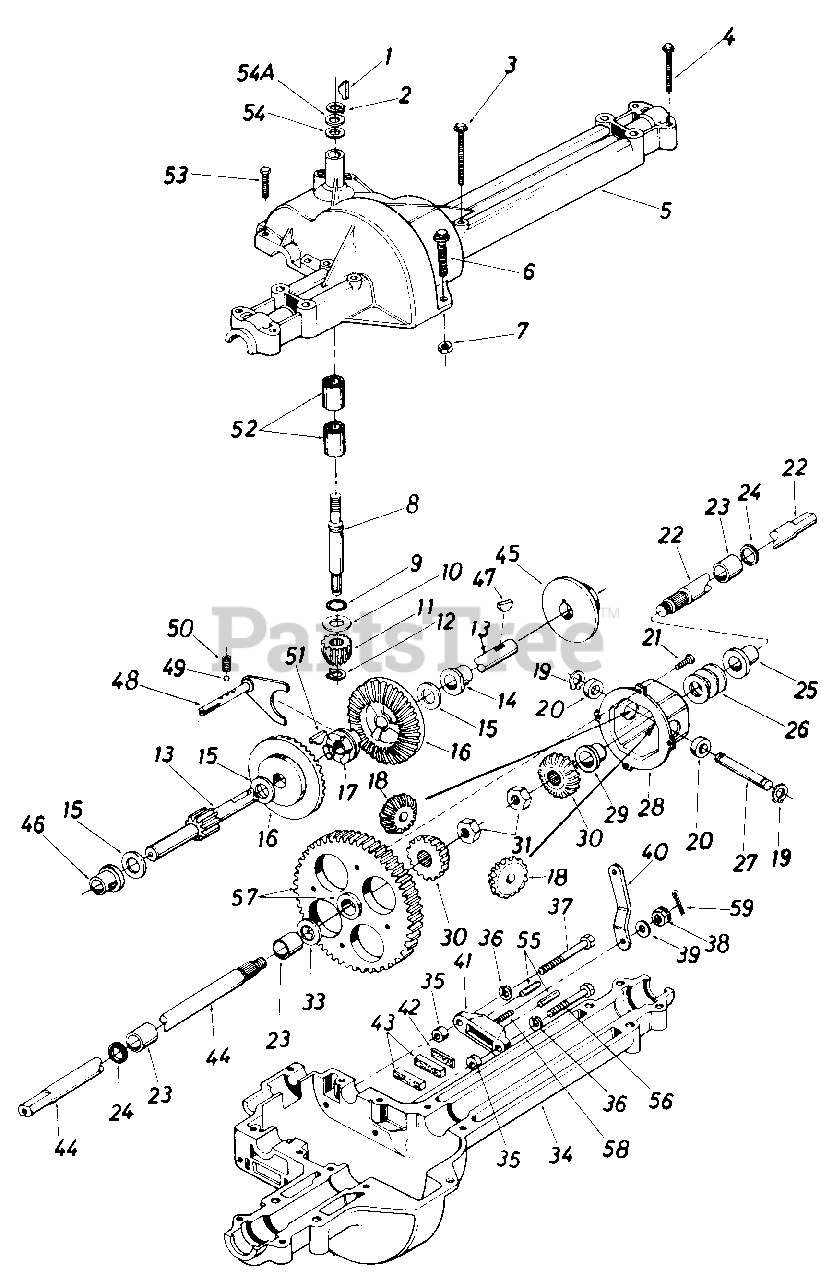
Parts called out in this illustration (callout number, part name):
1	#4 Hi-Pro Key 3/32 x 518" Dia.
2	Snap Ring .625" Shaft
3	Hex Bolt 1/4-20 x 1.75" Lg.
4	Hex Bolt 1/4-20 x 1.25" Lg.
5	Upper Housing
6	Hex Fl-Bolt 1/4-20 X .75" Lg.
7	Hex Nut 1/4-20 Thd.
8	Input Shaft
9	Squtle Seai 518" I.D.
10	Thrust Washer 518" I.D. x 1.25" O.D.
11	Pinion Input 14T
12	Retaining Ring 7116" Ext.
13	Drive Shaft-R.H.
14	Flange Brg. 518" I.D. x 3/4" Lg.
15	Fl-Wash.
16	Bevel Gear 42T
17	Clutch Collar
18	Miter Gear 15T
19	Snap Ring
20	Thrust Bearing 1/2" I.D. x 1.0" O.D.
21	Pan Head Scr. 1/4-20 X .50" Lg. w/Patch
23	Sleeve Bearing 3/4" I.D. x 1.0" Lg.
24	Oil Seal 3/4" I.D.
25	Flange Bearing 3/4" I.D. x 15/1 6" Lg.
26	Fl-Wash. .760" I.D. x 1.49" O.D.
27	Cross Shaft
28	Differential Housing Ass'y.
30	Miter Gear-H.D.
31	Hex Ins. L-Nut 1/2-20 Thd.
33	Fl-Wash. .75" I.D. x 1.5" O.D.
34	Lower Housing
35	Spacer .53" O.D. x 3/8" Lg.
36	L-Wash. 1/4" I.D.
37	Hex Bolt 1/4-20 x 1.50" Lg. (Grade 5)
38	Castle Nut 5/16-24 Thd.
39	Fl-Wash. .34" I.D. x .875" O.D.
40	Actuating Arm-R.H.
42	Puck Plate
43	Brake Puck
46	Flange Bearing 5/8" I.D. x 15/16" Lg.
47	Woodruff Key 3/16 Y 5/8 HT
48	Shift Fork Ass'y.
49	Ball Detent.250" Dia.
50	Spring Detent
51	#9 Hi-Pro Key 3/16" x 3/4" Dia. HT
52	Needle Brg. 5/8" I.D. x 1/2" Lg.
53	Hex Bolt 1/4-20 x 1.00" Lg.
54	Fl-Wash. 5/8" I.D. x .030
54A	Fl-Wash. 5/8" I.D. x .040
55	Actuating Pin 5/16" Dia.
56	Hex Bolt 1/4-20 x 1.50" Lg. (Grade 5)
57	Differential Gear 72T Ass'y. w/Bearing
58	Sq. Hd. Bolt 5/16-24 Thd.
59	Cotter Pin 3/32" Dia. x .50" Lg.
